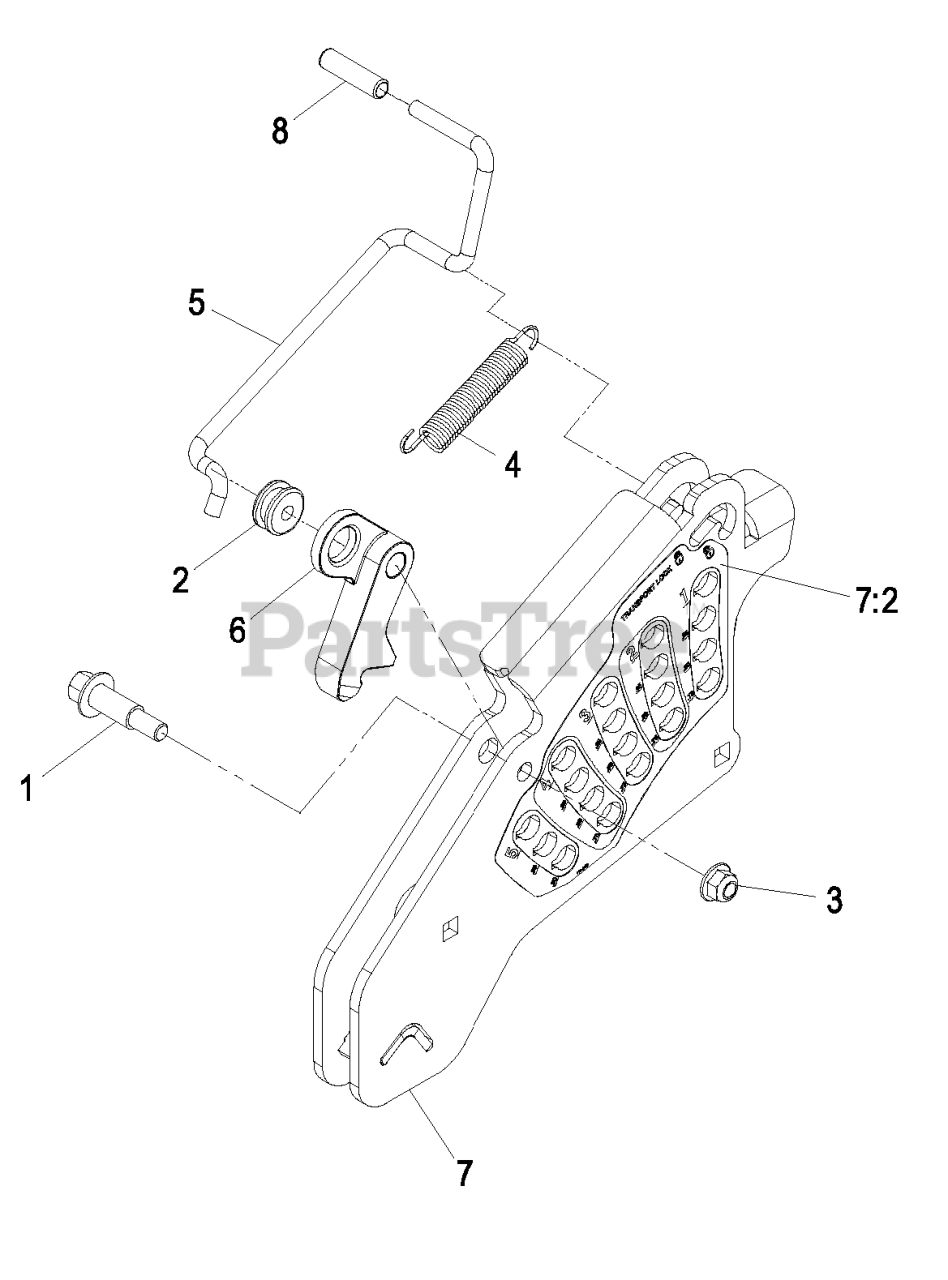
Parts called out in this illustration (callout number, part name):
1	BOLT-SHOULDER
2	GROMMET
3	NUT-HF, NI
4	SPRING-EXTENSION
5	ROD-LOCK, TRANSPORT
6	PAWL-TRANSPORT, HOC
7	HOC PLATE ASM
7:2	DECAL-HOC
8	GRIP-LEVER
